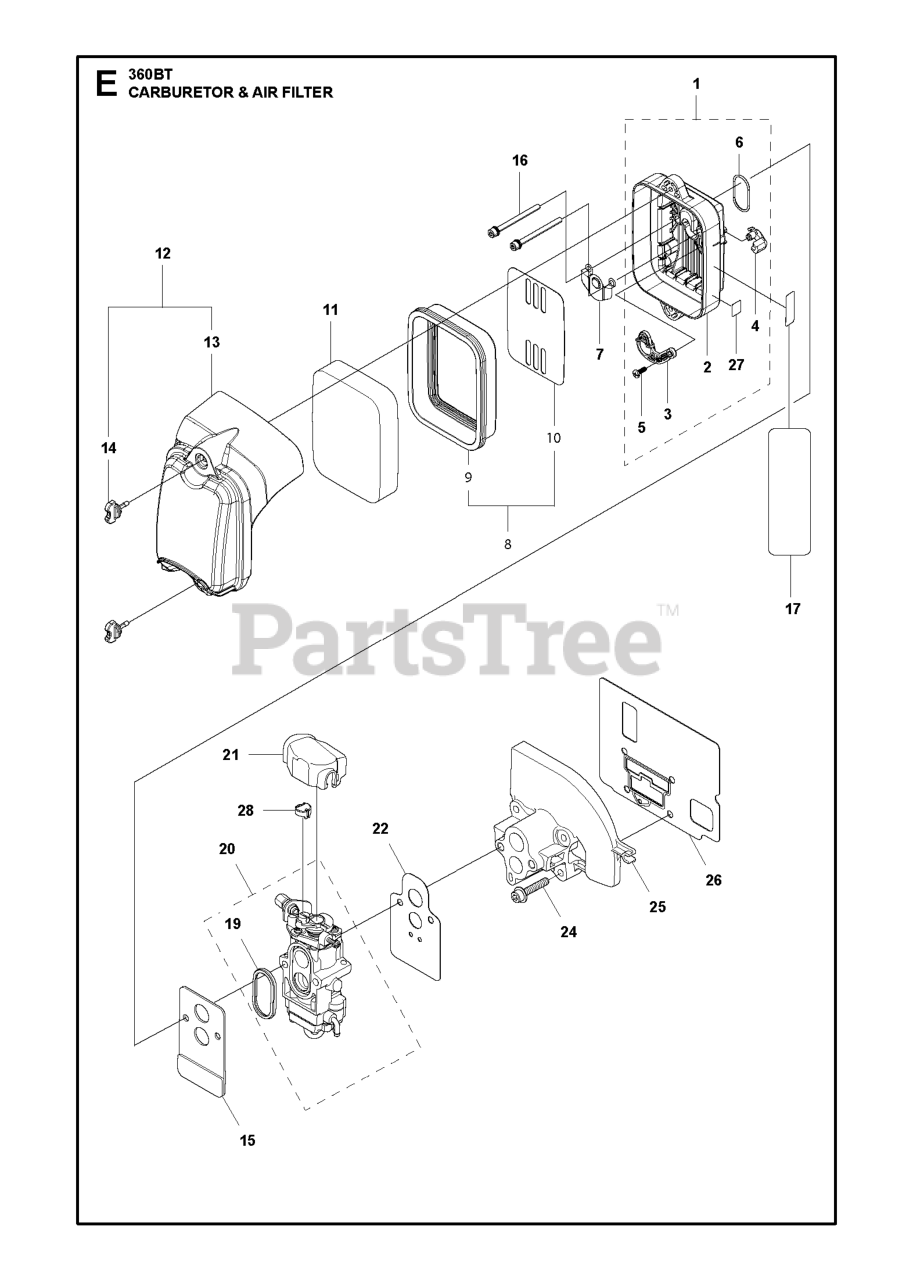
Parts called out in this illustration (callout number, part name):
1	AIR FILTER HOLDER ASSY
2	AIR FILTER HOLDER
10	SCREEN
11	AIR FILTER, ELEMENT
12	AIR FILTER COVER
13	AIR FILTER COVER
17	LABEL,CHOKE
20	CARBURETOR
